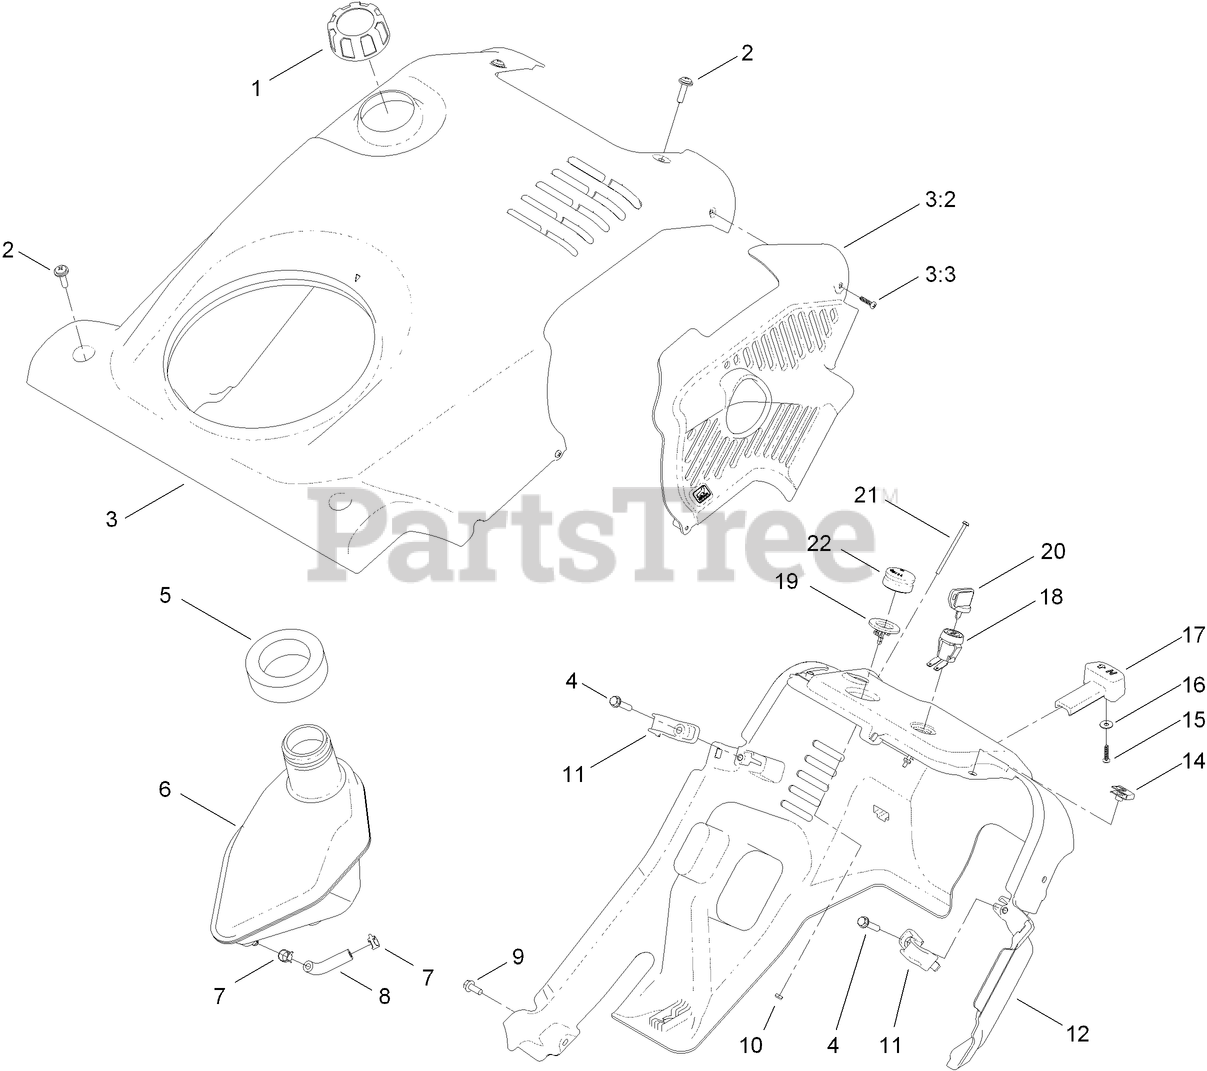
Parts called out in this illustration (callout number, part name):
1	4-CYCLE GAS CAP ASM
2	SCREW-PPH
3	SHROUD ASM
3:2	BAFFLE-EXHAUST
3:3	SCREW-PPH
4	SCREW-PLASTITE
5	SEAL-TANK
6	TANK-FUEL, GAS
7	CLAMP-HOSE
8	HOSE-FUEL
9	SCREW-HWH
10	NUT-HEX
11	CLIP-SHROUD
12	SHROUD-LOWER
15	SCREW-PPH
16	WASHER-PLAIN
17	KNOB-CHOKE
18	SWITCH
19	BODY-PRIMER
20	KEY-IGNITION
21	SCREW-HWH
22	BULB-PRIMER
